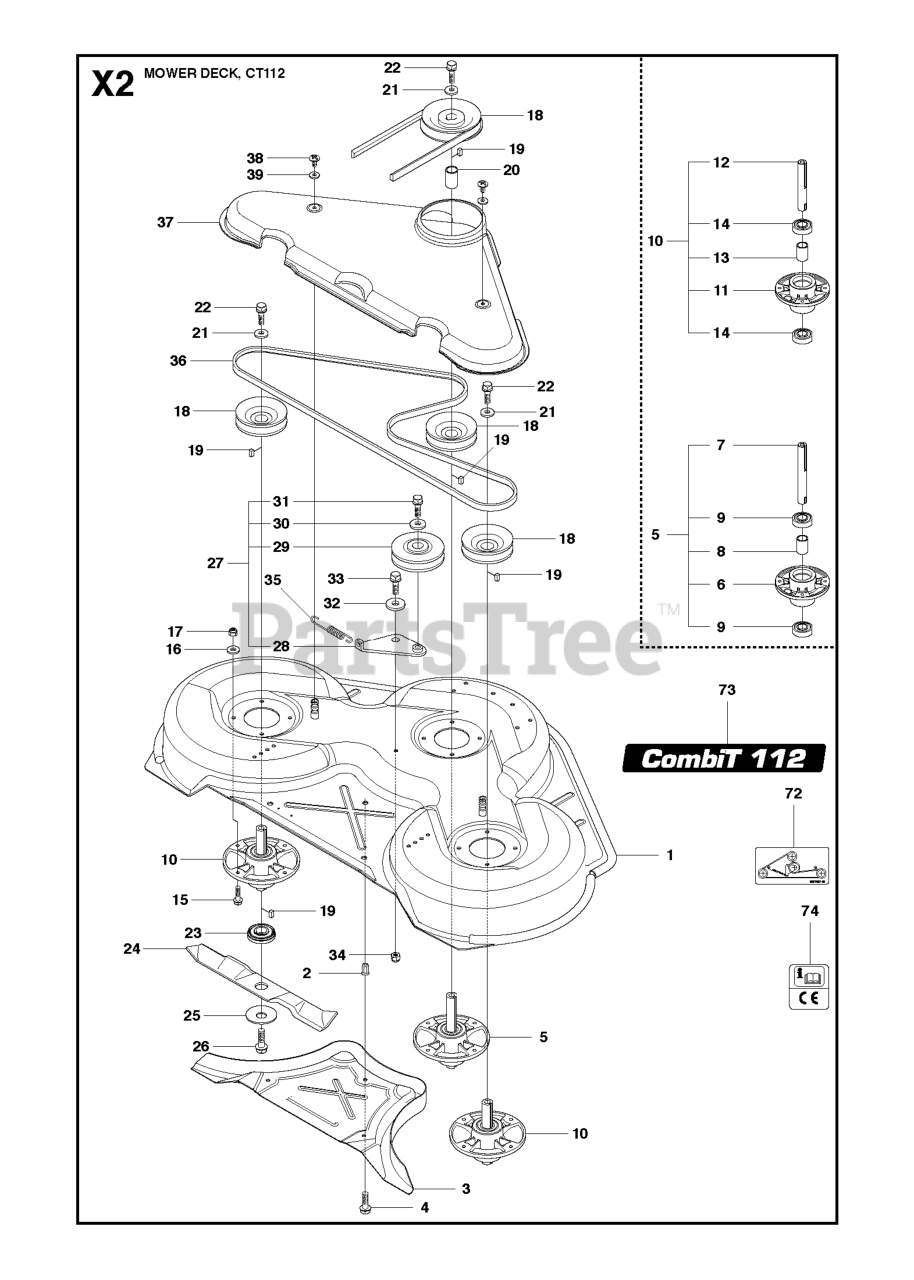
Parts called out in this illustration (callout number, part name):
6	BEARING HOUSING
9	BALL BEARING
11	BEARING HOUSING
14	BALL BEARING
16	WASHER BRB 8.4X17
17	LOCKNUT M8
27	BELT TENSIONER ASSY
28	BELT TENSIONING ARM
32	WASHER
34	LOCKNUT M8
36	BELT
37	BELT COVER
